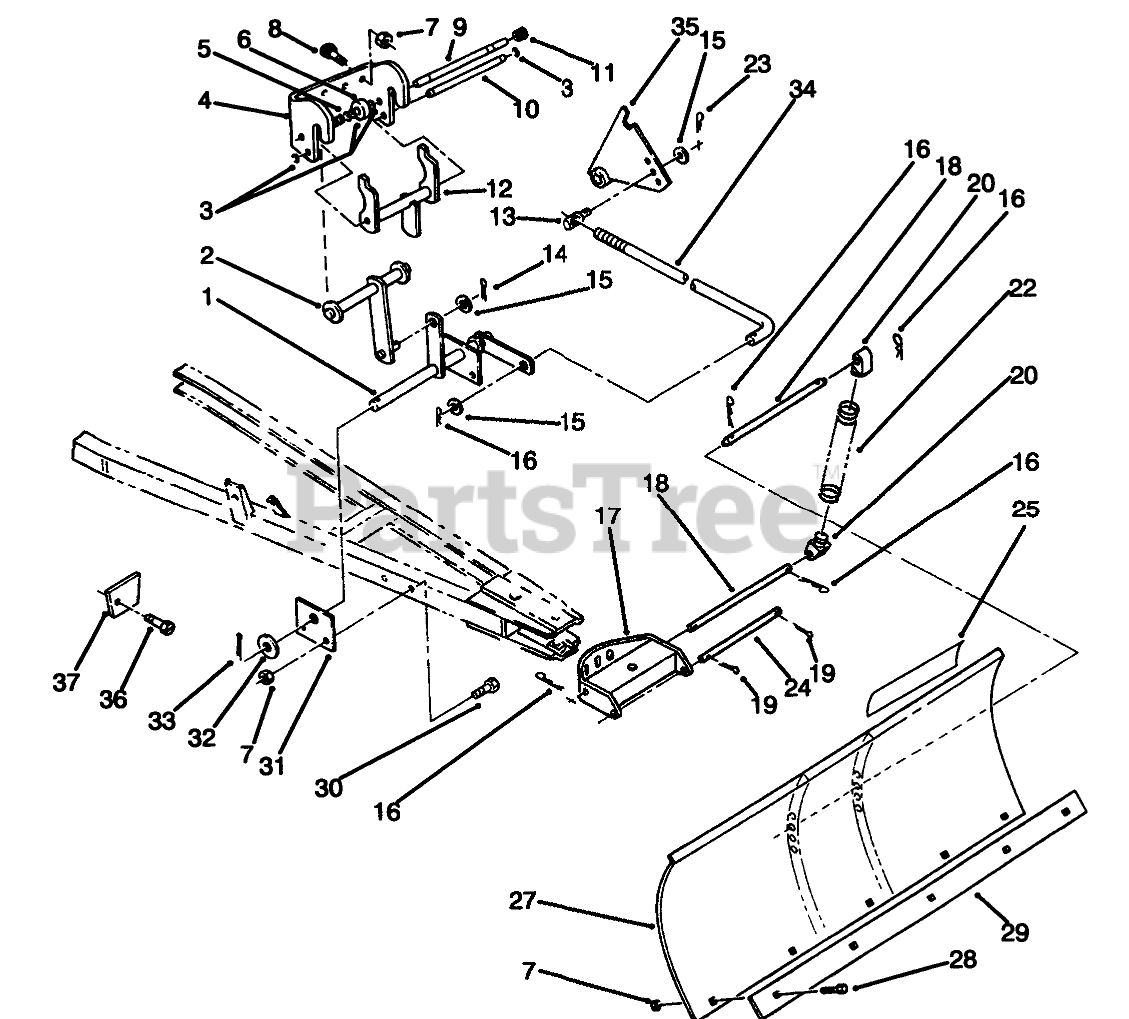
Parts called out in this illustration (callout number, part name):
1	Lift Arm
2	Arm
3	RING-RETAINING
4	Housing-Front Hitch
5	SPRING
7	NUT-LOCK, NI
8	SCREW-CARR
9	ROD-LOCK
10	ROD-LATCH PIVOT
11	CAP-ROD, PLUNGER
12	Latch-Front Hitch
13	STUD-TRUNION
14	PIN-COTTER
15	WASHER-FLAT
16	Hairpin
17	Decal
18	ROD-PIVOT, BLADE
19	PIN-COTTER
20	Lug
22	Spring-Return
23	Hairpin
24	ROD-LOWER
25	DECAL-ATTACHMENT
27	Blade
28	SCREW-CARR
29	PLATE - BLADE EDGE
30	SCREW-HH
31	Plate
32	WASHER-FLAT
33	PIN-COTTER
35	Plate
36	DECAL-PTO / CHOKE
37	Stop-Steering Spindle
